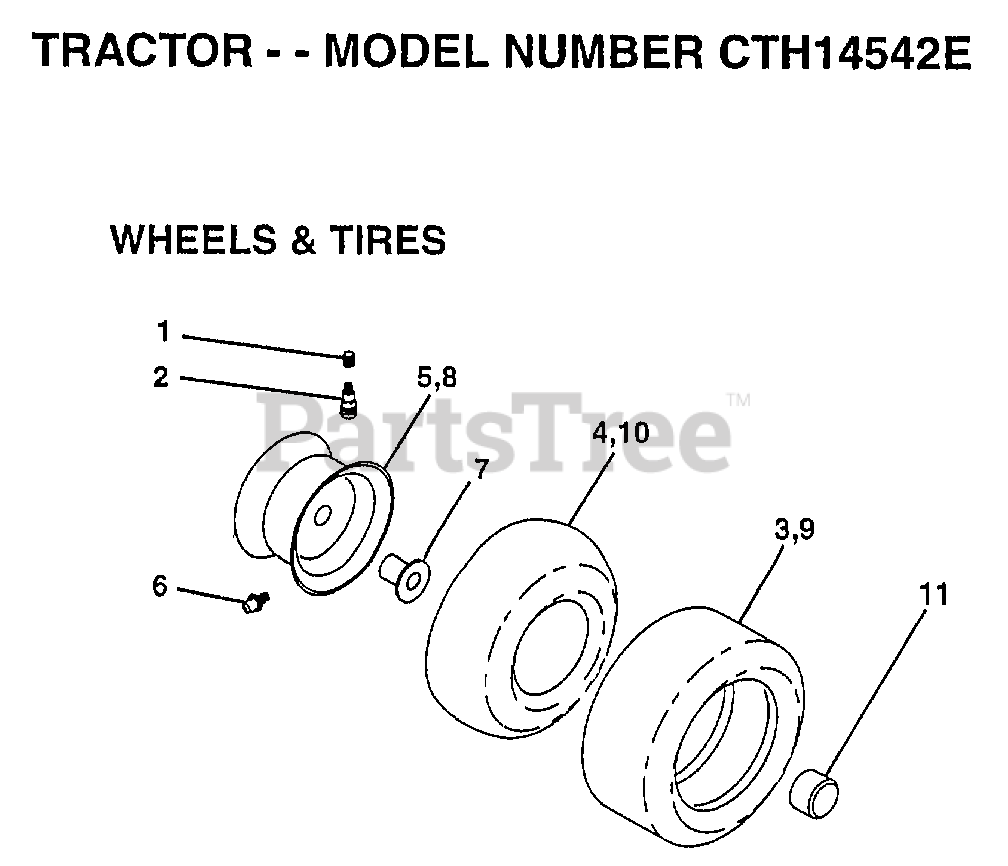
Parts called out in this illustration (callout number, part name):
1	VALVE CAP
2	VALVE STEM LT
4	TUBE.5.3/4.5/6
5	RIM.FRONT.6.YELLO
6	FITTING LT
7	"FLANGE, BEARING"
10	TUBE.18X9.5-8
11	HUB CAP
